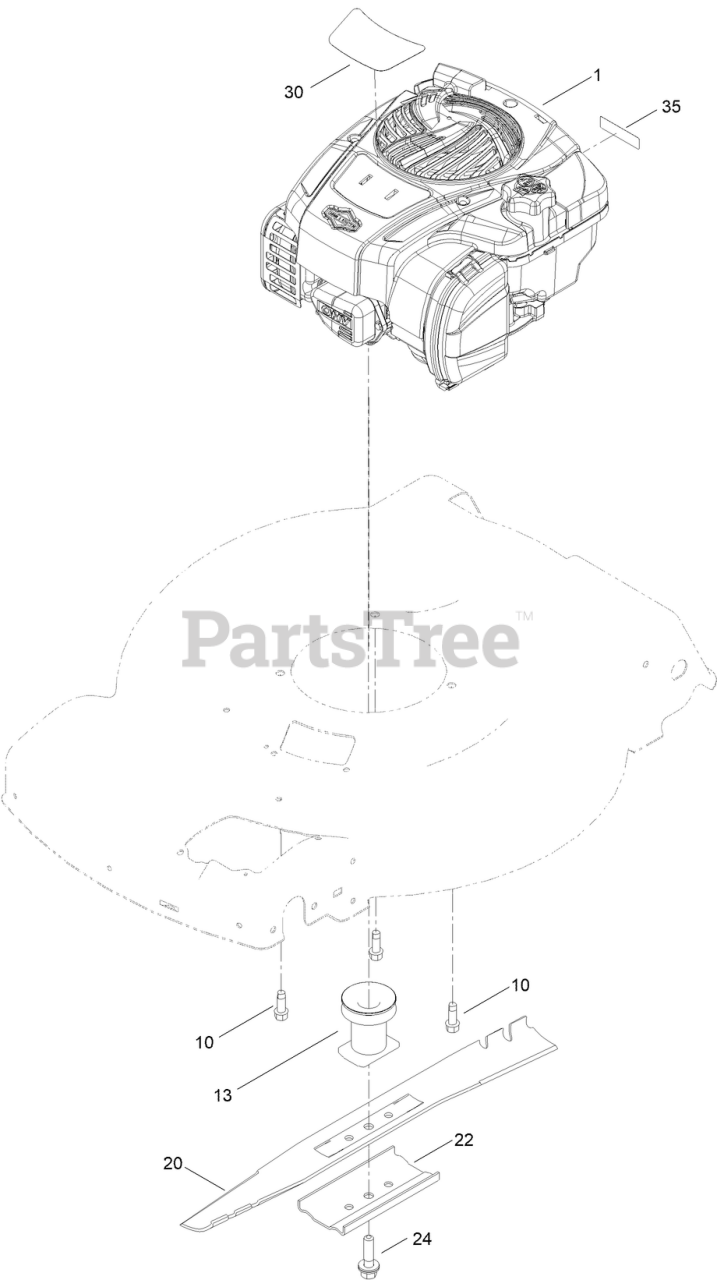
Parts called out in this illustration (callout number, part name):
1	ENGINE-BRIGGS, 625 EXI ZS
10	SCREW-TAPTITE
13	DRIVER-BLADE
20	BLADE-22 INCH
22	SUPPORT-BLADE
24	BOLT-BLADE
30	DECAL-BRIGGS 625 EX
35	DECAL-ARRESTOR, SPARK
